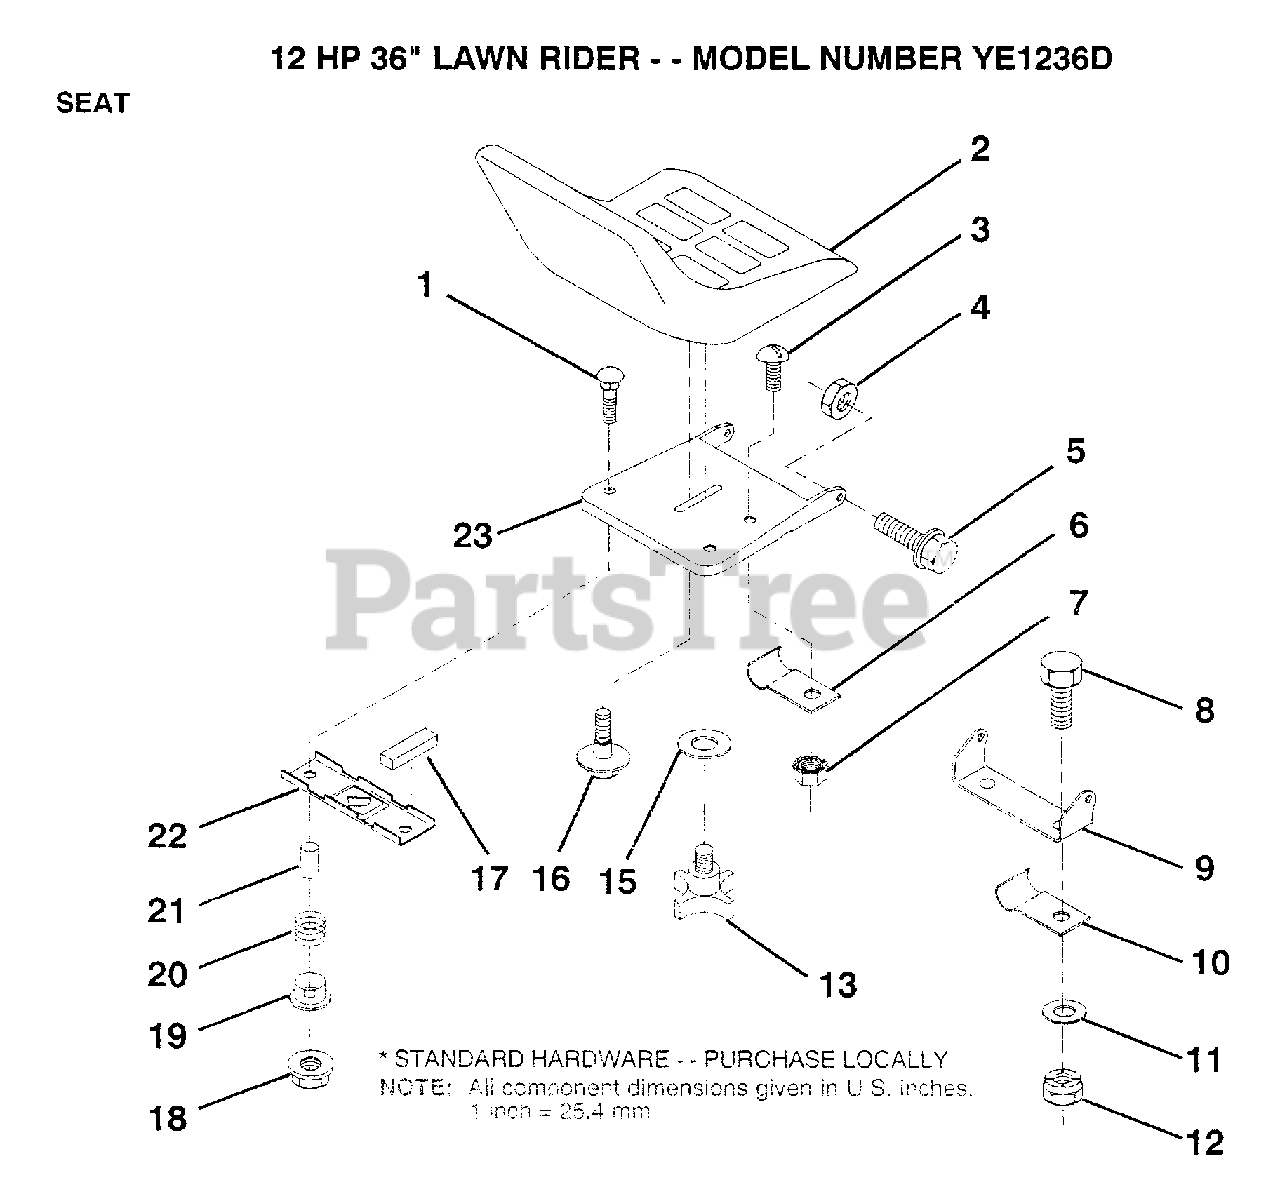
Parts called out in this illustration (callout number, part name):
7	"NUT,KEPS"
10	"CLIP,INSULATOR"
11	WASHER
13	"KNOB 1/2"" YT"
15	WASHER
16	"BOLT,SHOULDER"
17	STRIP FORM
19	BUSHING
20	SPRING
21	SPACER SPLIT
22	BRKT SWITCH
